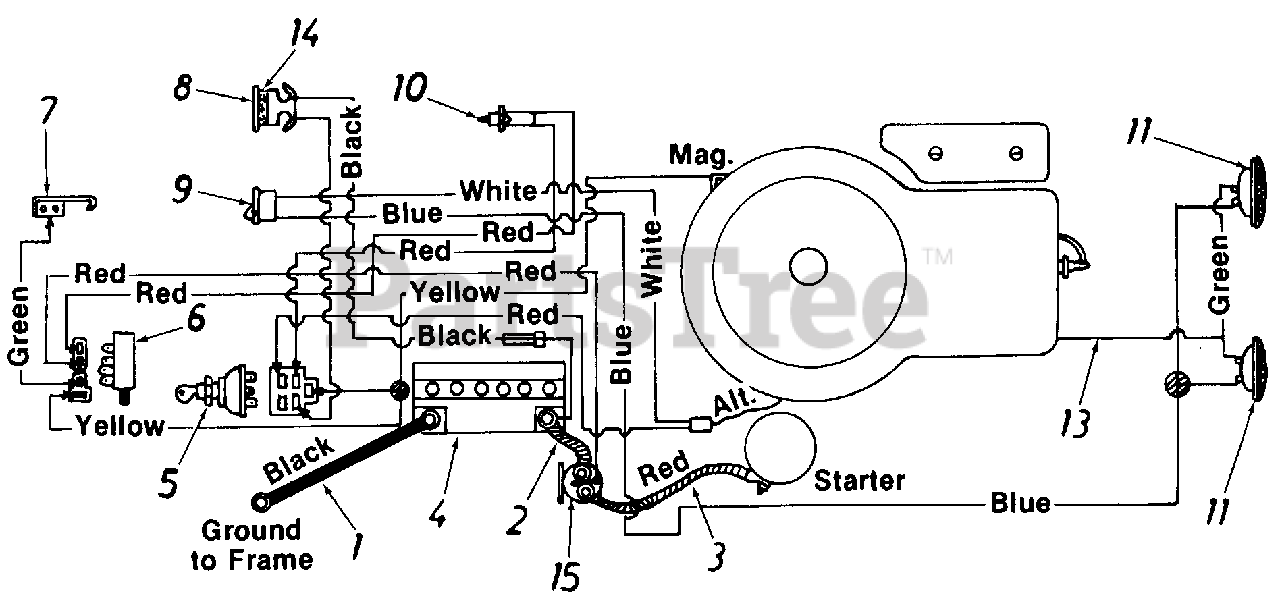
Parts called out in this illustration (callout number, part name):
1	Ground Wire-11.5" Lg.
2	Electric Wire (Red)-11.5" Lg.
3	Electric Wire-7.25" Lg.
4	Battery
5	Ignition Switch
6	Safety Switch
7	Spring Switch
8	Ammeter
9	Light Switch
10	Safety Switch
11	Headlight
13	Ground Wire
14	Foam Strip
15	Solenoid
